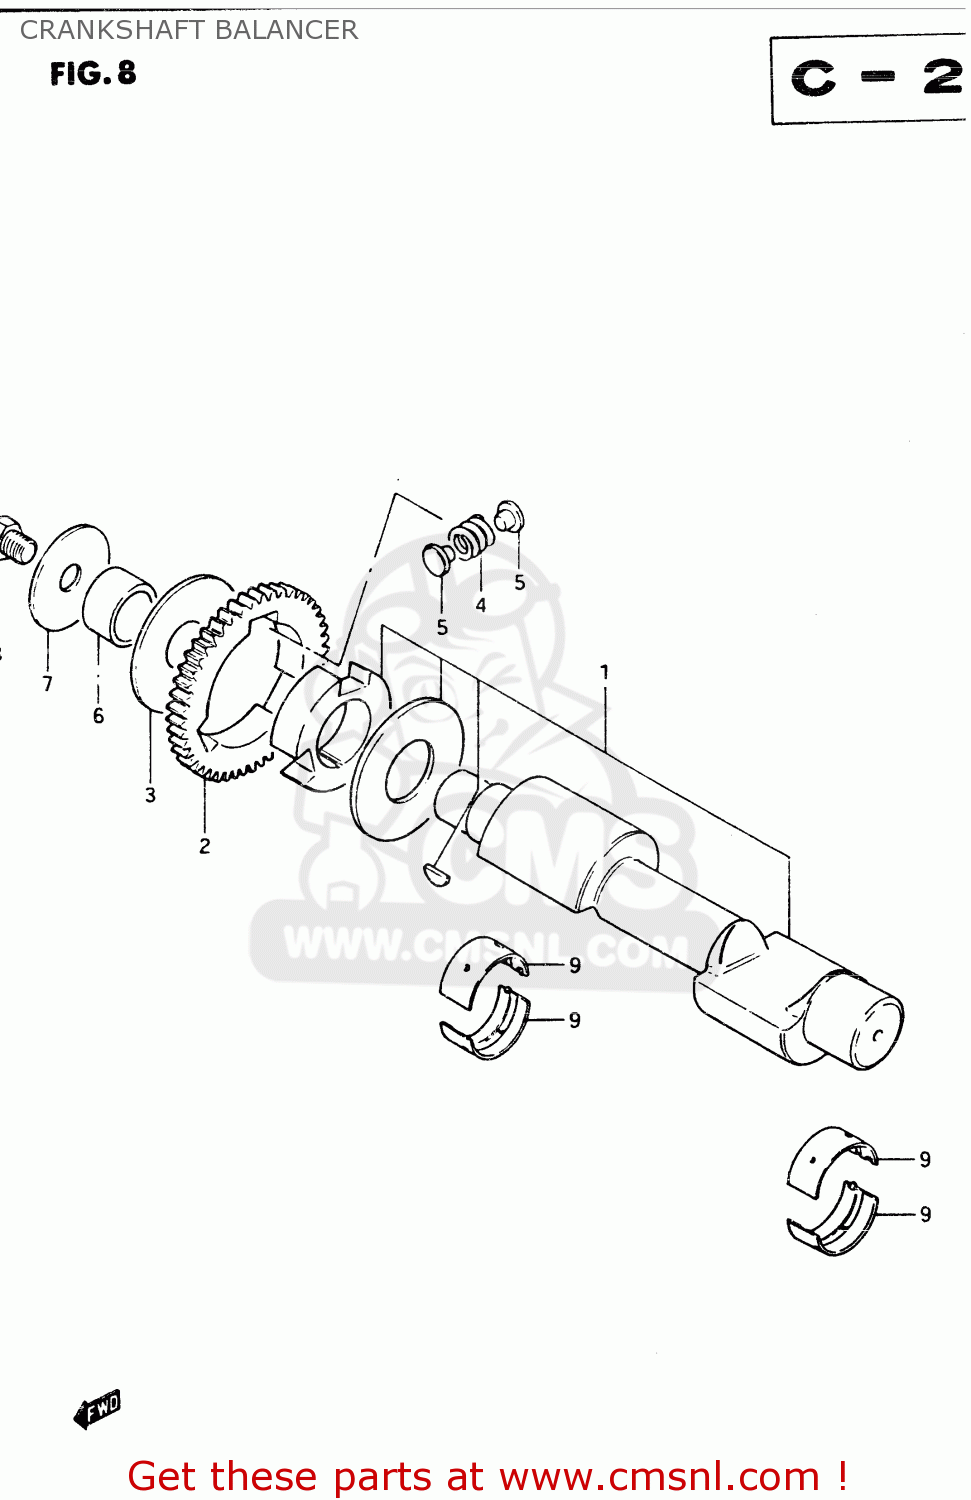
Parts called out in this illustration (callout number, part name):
1	BALANCER,CRANKSHAFT
2	GEAR,CRANK BALANCER DRIVE
3	WASHER
4	SPRING
5	PIN
6	SPACER
7	WASHER(12X50X3)
8	BOLT
9	METAL CRANKSHAFT
